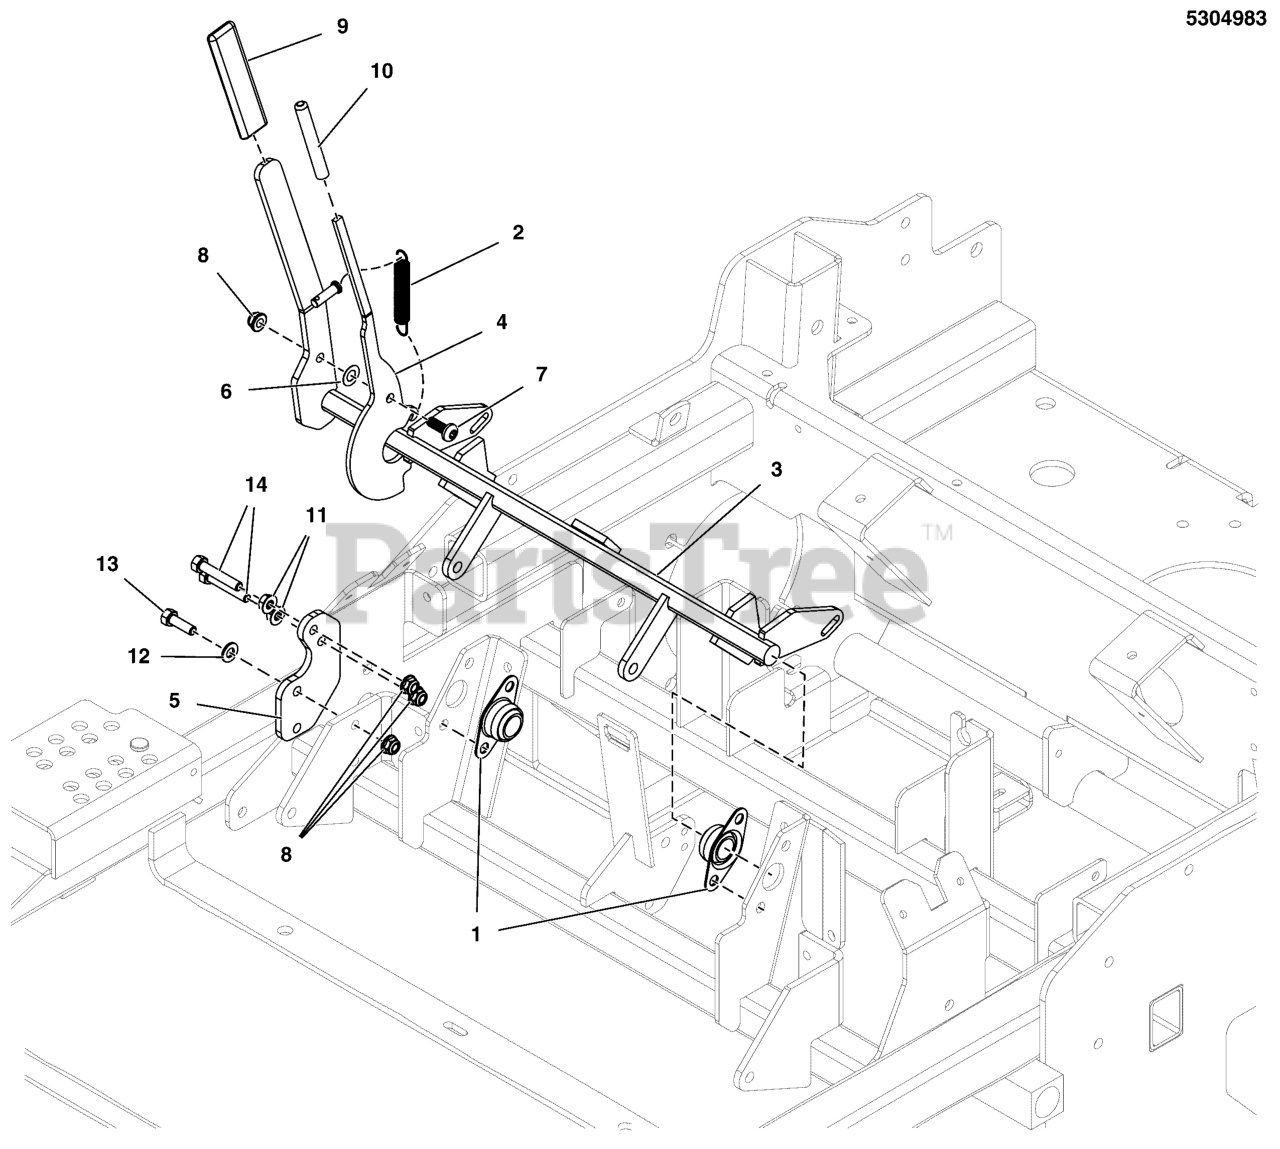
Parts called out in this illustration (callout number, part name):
1	BEARING, 3/4" FLANGED, BRONZE
2	SPRING-EXT, .500 OD X 3.50 LG X .058 WR
3	WELD, BRAKE SHAFT, F210 CE - BLK
4	PLATE, BRAKE LOCK, CE HANDLE - BLK
5	MOUNT, CE PARKING BRAKE LOCK - RED
6	WASHER,WAVE,M10
7	SCREW, TRUSS HD TORX DR5/16-18X0.875 BLK
8	NUT, 5/16-18 HEX NYLOCK FLANGE
9	GRIP, FOAM, 1/4 X 1 X 4.1
10	COVER, VINYL HANDLE
11	NUT, 5/16-18 HEX SERRATED FLANGE (SMALL)
12	WASHER, 5/16" SAE
13	BOLT, 5/16-18 X 1 GD5 CZ
14	BOLT, 5/16-18 X 1-3/4 GD5 CZ
